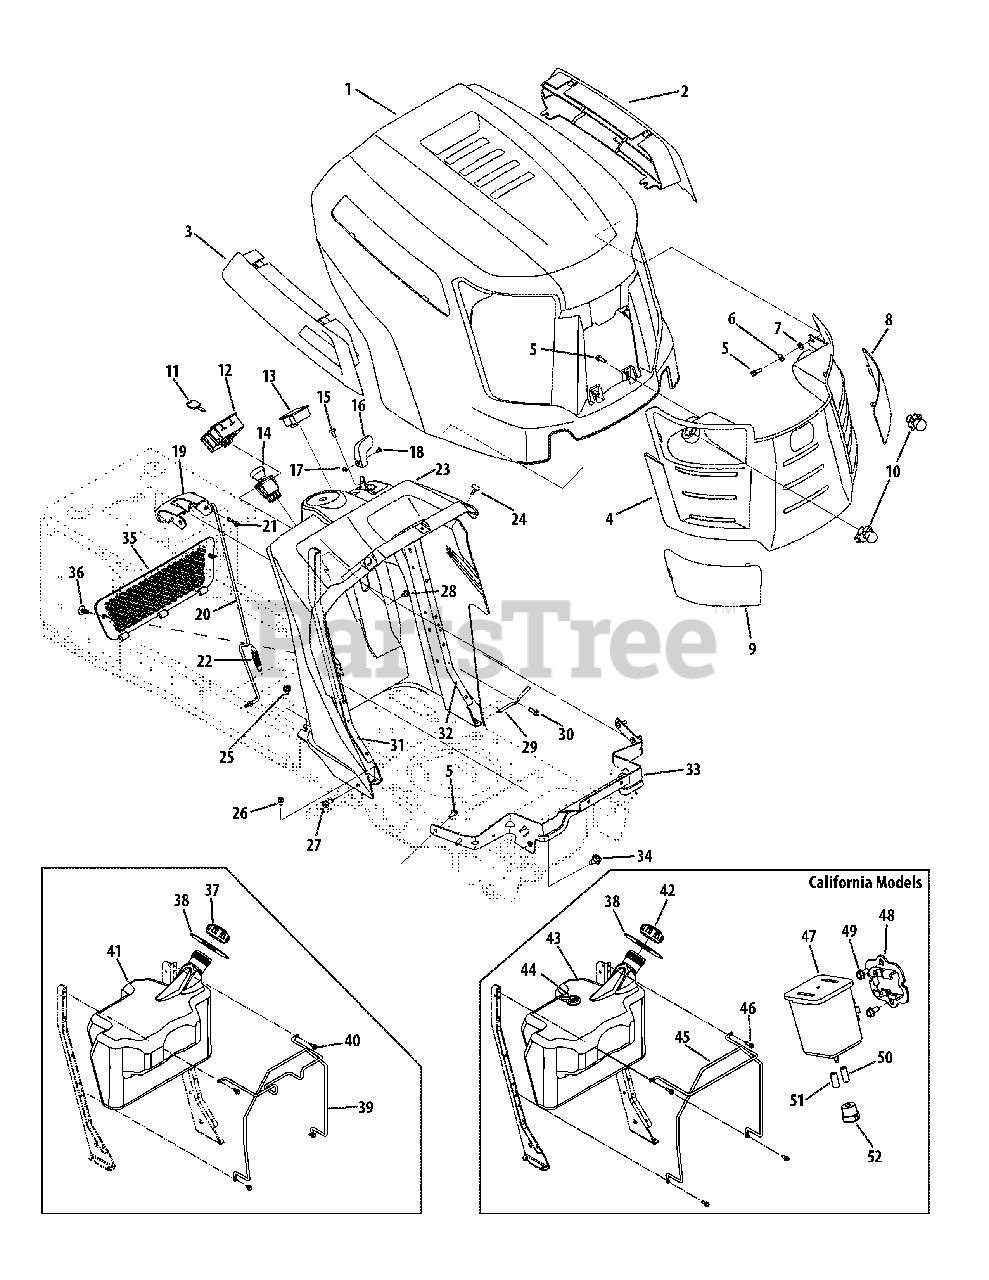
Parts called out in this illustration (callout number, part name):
1	Hood
2	LH Hood Scoop
3	RH Hood Scoop
4	Grille Asm
5	Hex Washer BosScrew™, 1/4 Dia. x .750
6	Flat Washer, .271 x .630 x .065
7	Lock Washer, 1/4
10	Socket, Headlight
11	Key
12	Key Switch
13	Indicator Meter
14	Electric PTO
15	Screw, 1/4-14 x .625
16	Throttle Knob
17	Hex Nut, #8-32
18	Screw, #8-32 x .375
19	Parking Brake/Cruise Control Lever
20	Control Rod
21	Bow-Tie Cotter Pin
22	Extension Spring, .500 x 2.733
23	Dash Panel - LTX1042 & LTX1045
23	Dash Panel - LTX1046 & LTX1050
25	Hex Washer Screw, 5/16-18 x .750
26	Hex Washer Screw, 1/4-20 x .500
27	Screw, 5/16-18 x .750
28	Hex Washer Screw, 1/4-20 x .625
29	Bent Lever Rod
30	Hex Washer Screw, 1/4-15 x .750
31	Dash Support, RH
32	Dash Support, LH
33	Hood Pivot Bracket
34	Shoulder Screw, 5/16-18 x .43 x .29
36	Ratchet Clip
37	Fuel Cap
38	Fuel Tank Gasket
39	Fuel Tank Support Rod
40	Hex Washer Screw, 1/4-20 x .625
41	Fuel Tank
42	Fuel Cap
43	Fuel Tank
44	Rollover Valve
45	Fuel Tank Support Rod
46	Hex Washer Screw, 1/4-20 x .750
47	Carbon Canister
48	Canister Adapter Bracket
49	Hex Washer Screw, 5/16-18 x .750
50	Fuel Hose, 3/16 White
51	Fuel Hose, 7/32 Yellow
52	Canister Vent Filter
